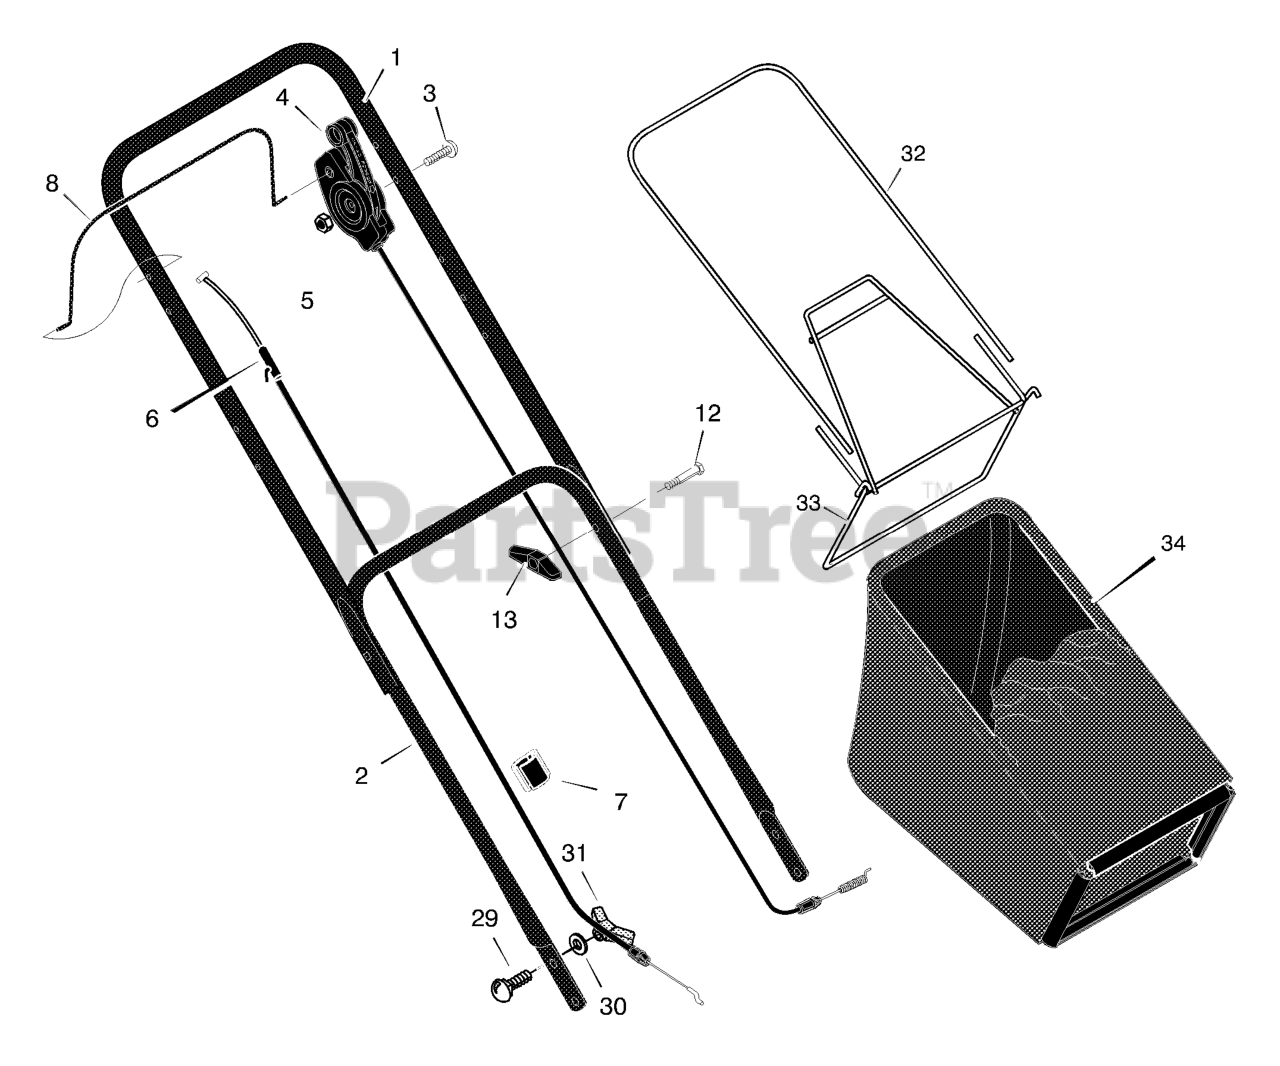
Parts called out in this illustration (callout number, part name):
1	Handle, Upper (Gray)
2	Handle, Lower (Gray)
4	Control, Drive
5	Locknut
6	Cable, Stop
7	Fastener, Single Cable
8	Lever, Stop
13	Knob
16	Guide, Rope
29	Bolt, Carriage
31	Knob, Plastic
32	Tube, Bag
33	Frame Assembly
34	Bag, Cloth - Gray
